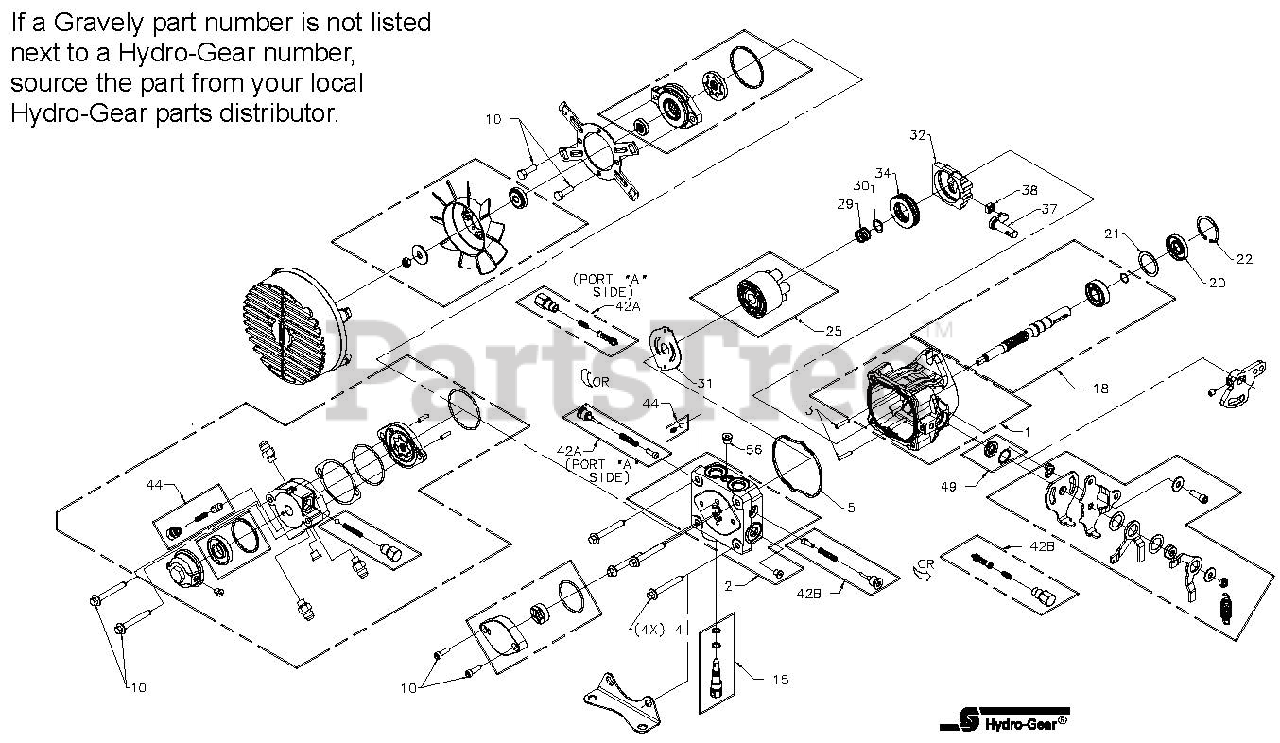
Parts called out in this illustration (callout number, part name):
1	Kit, Housing
2	Kit, End Cap W/PPT & STD
3	Pin, .219 x 1
4	Hex, Flange Bolt M8-1.25 x 60mm
5	Kit, Chg Pump
10	Screw, Cap M6 x 1 x 25mm
15	Kit, Bypass Valve
18	Kit, Pump Shaft 15mm Key
20	Seal, Lip 17 x 40 x 7
21	Washer 1.23 x 1.56 x .04
22	Ring, Ret 1.56 Int
25	Kit, 10 CC Block
29	Spring, Block
30	Washer, Thrust .59 x .78 x .04
31	Plate, Valve
32	Swashplate 10cc
34	Bearing, Thrust Ball 30 x 52 x 13
37	Arm, Trunnion 10 CC
38	Guide, Slot
42	Kit, Shock Valve 200 Bar
44	Kit, Chg Relief
49	Kit, BDP-10l Seal
56	Plug 7/16-20 (Metal)
NS	Kit, Overhaul Seal
